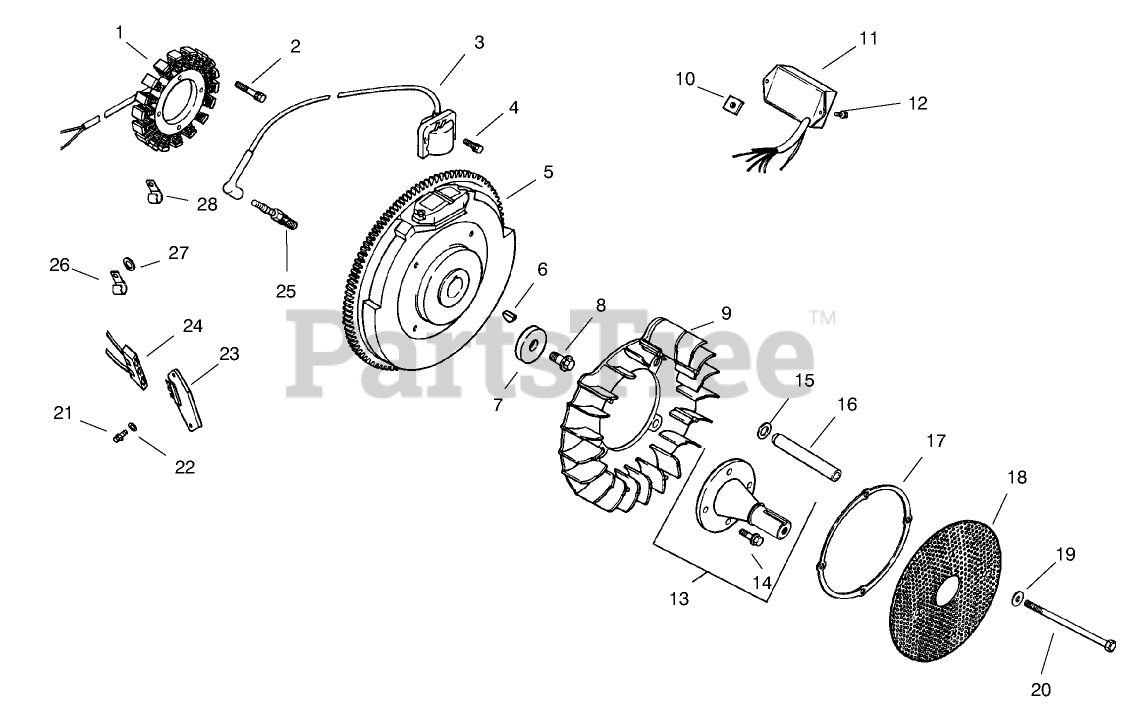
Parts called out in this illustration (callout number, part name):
1	Kit, 15 amp stator (Incl. 24 126 71 bracket)
2	Screw
3	Module-Ignition
4	Screw-HSH
5	Flywheel
6	Key
7	Washer
8	Screw
9	Fan
10	Nut-Plastic
11	Module, speed adv.
12	Screw
13	Kit, front drive shaft (Includes 14)
14	Screw
15	Washer, sping
16	Spacer
17	Ring-Support
18	Screen-Grass
19	Washer
20	Screw-Hex
21	Screw
22	Washer
23	Rectifier-Regulator
24	Connector
25	Plug-Spark
26	Clamp
27	Washer
28	Clip
